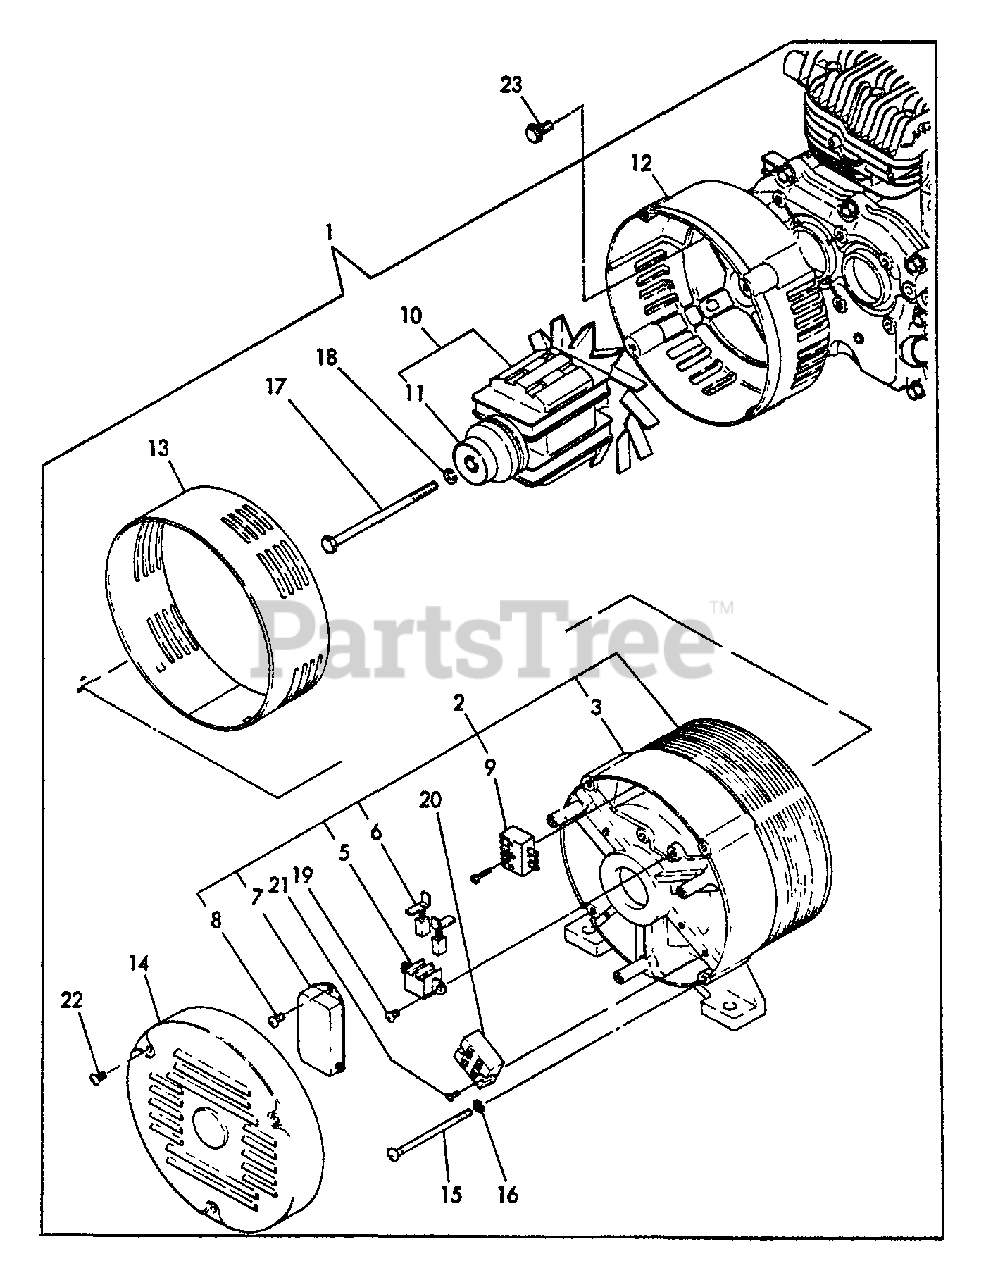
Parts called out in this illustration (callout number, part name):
1	GENERATOR 3.8KVA
2	STATOR ASSY
3	COVER - REAR
5	HOLDER, BRUSH
6	BRUSH
7	A.V.R.
8	SCREW - 4×14
9	RECTIFIER
10	ROTOR ASSY
11	BEARING, BALL
12	COVER, FRONT
13	CLAMP
14	COVER, END
15	BOLT, THROUGH
16	LOCKWASHER - 6
17	BOLT
18	LOCKWASHER - 10
19	SCREW - 5×14
20	TERMINAL
21	SCREW - 5×14
22	SCREW - 4×8
23	BOLT - 8×20 -- PLATED
